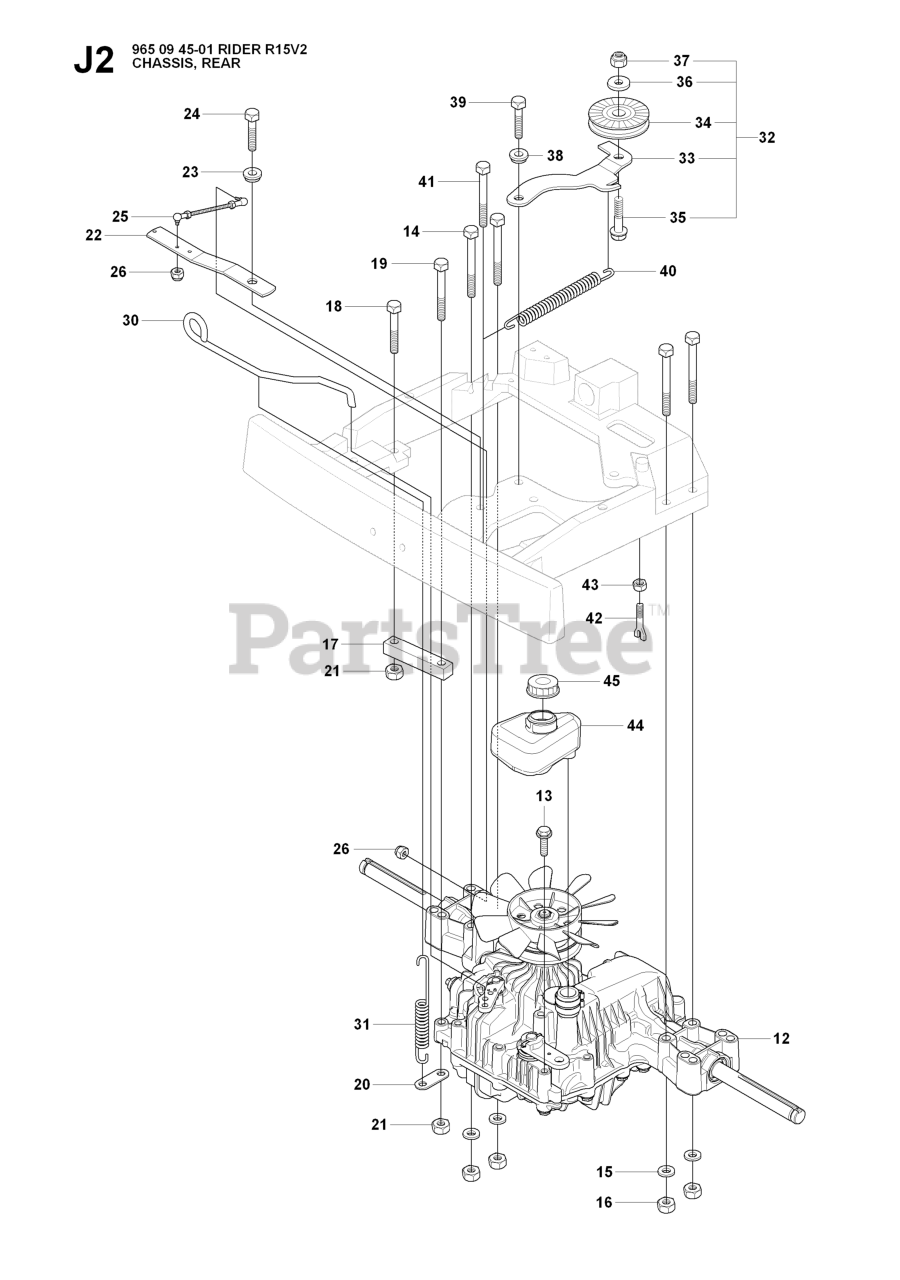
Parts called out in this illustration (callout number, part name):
12	HYDROSTAT 7A646024070
15	WASHER BRB 8.4X17
16	NUT
21	NUT
23	WASHER
24	SCREW 8X20
26	LOCKNUT M5
33	TENSIONER
35	SCREW
37	LOCKNUT M8
38	WASHER
39	SCREW 8X20
43	NUT
45	TANK CAP
